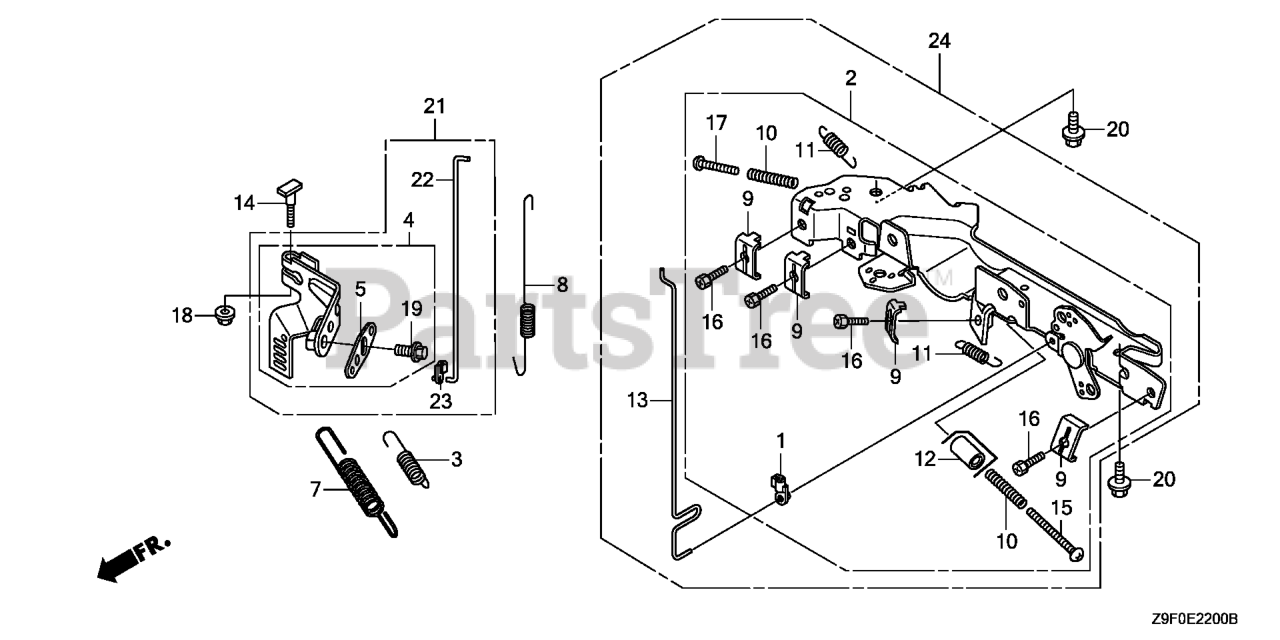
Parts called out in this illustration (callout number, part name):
1	JOINT, ROD
2	CONTROL ASSY.
3	SPRING, STARTER
4	ARM, GOVERNOR
5	ARM, SUB
7	SPRING, GOVERNOR
8	SPRING, THROTTLE RETURN
9	HOLDER, CABLE
10	SPRING, CONTROL ADJUSTING Use from Engine SN 2327377.
11	SPRING, CABLE RETURN
13	ROD, CHOKE CONTROL
14	BOLT, GOVERNOR ARM
15	SCREW, PAN (5X45)
16	BOLT, RECESSED (5X16)
17	SCREW, PAN (5X30)
18	NUT, FLANGE (6MM)
19	BOLT, FLANGE (6X10)
20	BOLT, FLANGE (6X14)
21	ARM KIT, GOVERNOR
22	ROD, GOVERNOR
23	BUSH, LINKAGE
24	KIT, CONTROL ASSY.
